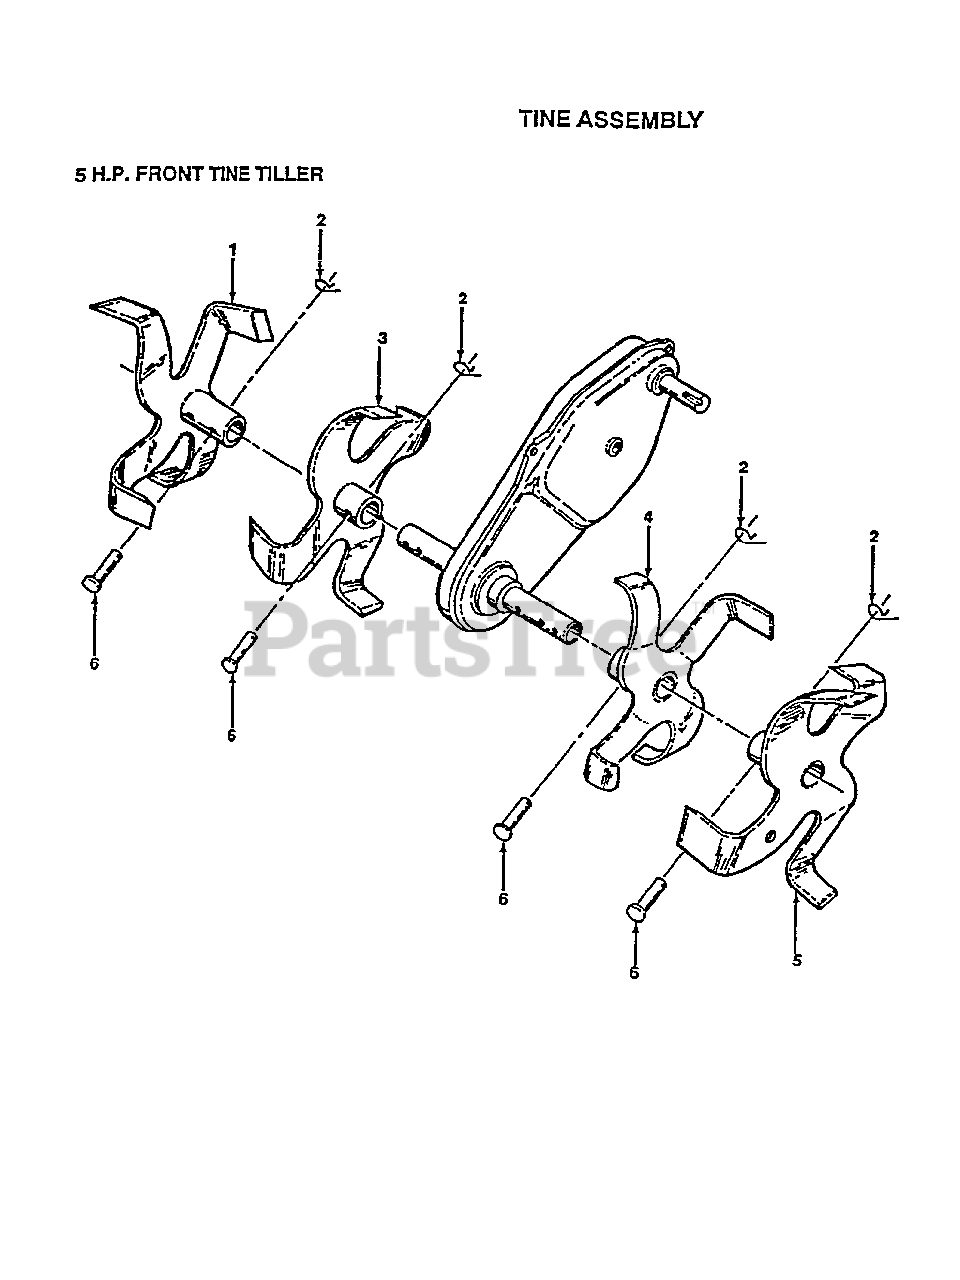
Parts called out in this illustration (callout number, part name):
1	TINE WELDMENT TI
2	RETAINER.SPRING
3	TINE TI
4	TINE TI
5	TINE WELDMENT TI
6	RIVET.PAN HD.1.75
